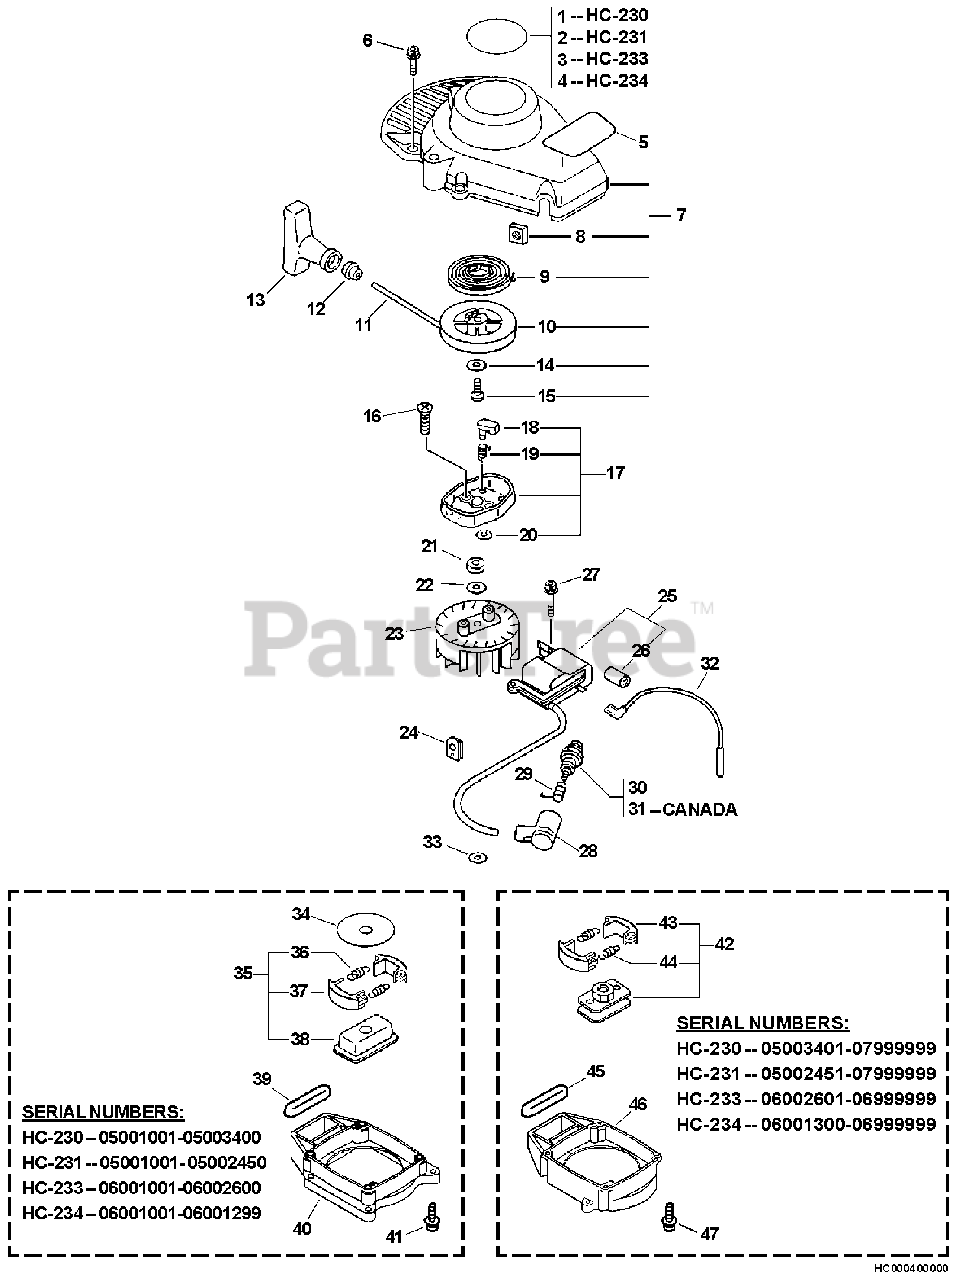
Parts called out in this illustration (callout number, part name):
1	LABEL - MODEL HC-230
2	LABEL - MODEL HC-231
3	LABEL - MODEL HC-233
4	LABEL - MODEL HC-234
5	LABEL - CAUTION
6	SCREW - 5X16
7	STARTER ASSY
8	NUT - 5 -- SQUARE
9	SPRING, REWIND
10	REEL, ROPE
11	ROPE, STARTER
12	GUIDE, ROPE
13	GRIP, STARTER
14	WASHER
16	SCREW - 6X14
17	STARTER PAWL ASSY
18	PAWL, STARTER
19	SPRING, RETURN
20	RING, RETAINING - 4
21	NUT - LEFT HAND
22	WASHER - 8
23	FLYWHEEL
25	COIL, IGNITION
26	TUBE, INSULATOR
27	SCREW - 5X16
28	CAP, SPARK PLUG
29	TERMINAL, SPARK PLUG CAP
30	SPARK PLUG -- BPM-8Y
31	SPARK PLUG -- BPMR-8Y
32	LEAD - GROUND
33	WASHER, CLUTCH
34	PLATE, CLUTCH
35	CLUTCH ASSY
36	SPRING, CLUTCH
37	SHOE, CLUTCH
38	HUB, CLUTCH
39	CUSHION, FUEL TANK
40	CASE, CLUTCH
41	SCREW - 4X14
42	CLUTCH ASSY
43	SHOE, CLUTCH
44	SPRING, CLUTCH
45	CUSHION, FUEL TANK
46	CASE, CLUTCH
47	SCREW - 4X14
